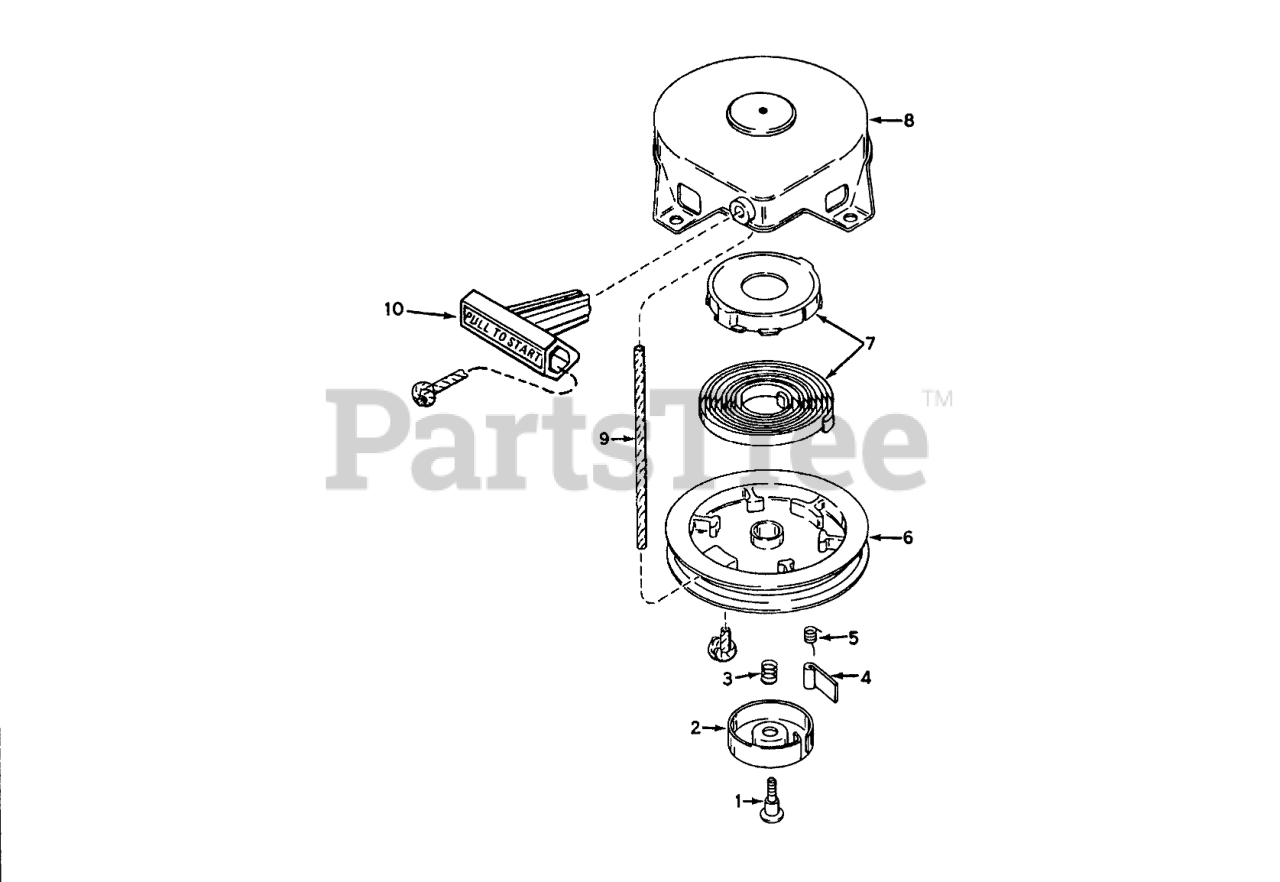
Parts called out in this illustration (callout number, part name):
2	Retainer
3	Spring-Brake
4	Dog-Starter
5	Spring-Dog
7	Spring & Keeper Assy
8	Housing-Starter
9	Rope-Starter (98 cut to length)
10	Handle-Starter
